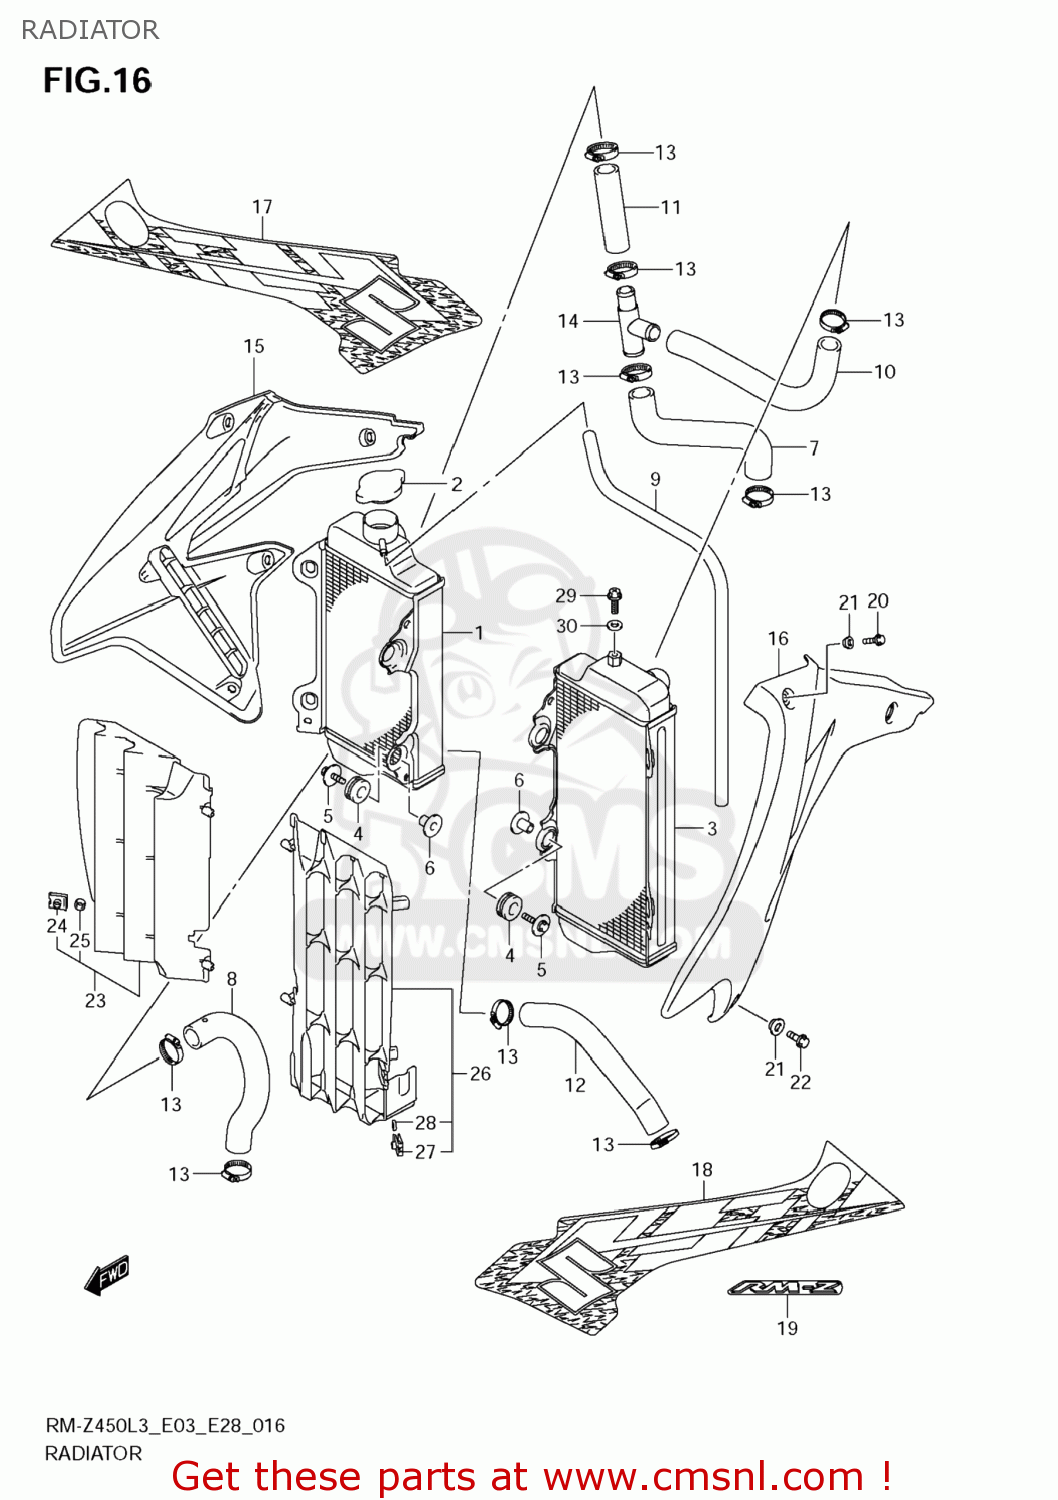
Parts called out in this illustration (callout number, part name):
1	RADIATOR,WATER,R
2	CAP,RADIATOR
3	RADIATOR,WATER,L
4	CUSHION,RADIATOR LWR
5	BOLT(6X25)
6	SPACER(6.5X10.5X14.1)
7	HOSE,RADIATOR INLET
8	HOSE,RADIATOR OUTLET
9	HOSE(5X8X1000)
10	HOSE,RADIATOR JOINT UPR NO.1
11	HOSE,RADIATOR JOINT UPR NO.2
12	HOSE,RADIATOR JOINT LWR
13	CLAMP
14	JOINT,RADIATOR HOSE
15	COVER,RADIATOR,R
16	COVER,RADIATOR,L
17	TAPE,RADIATOR COVER,R
18	TAPE,RADIATOR COVER,L
19	EMBLEM,RADIATOR COVER
20	BOLT(6X12)
21	WASHER,FR FENDER
22	BOLT
23	LOUVER,RADIATOR,R
24	NUT
25	SPACER(6.2X10X2.2)
26	LOUVER,RADIATOR,L
27	NUT
28	SPACER(6.2X10X2.2)
29	UNION BOLT,AIR VENT
30	GASKET(6.4X11.5X0.8) (NAS)
